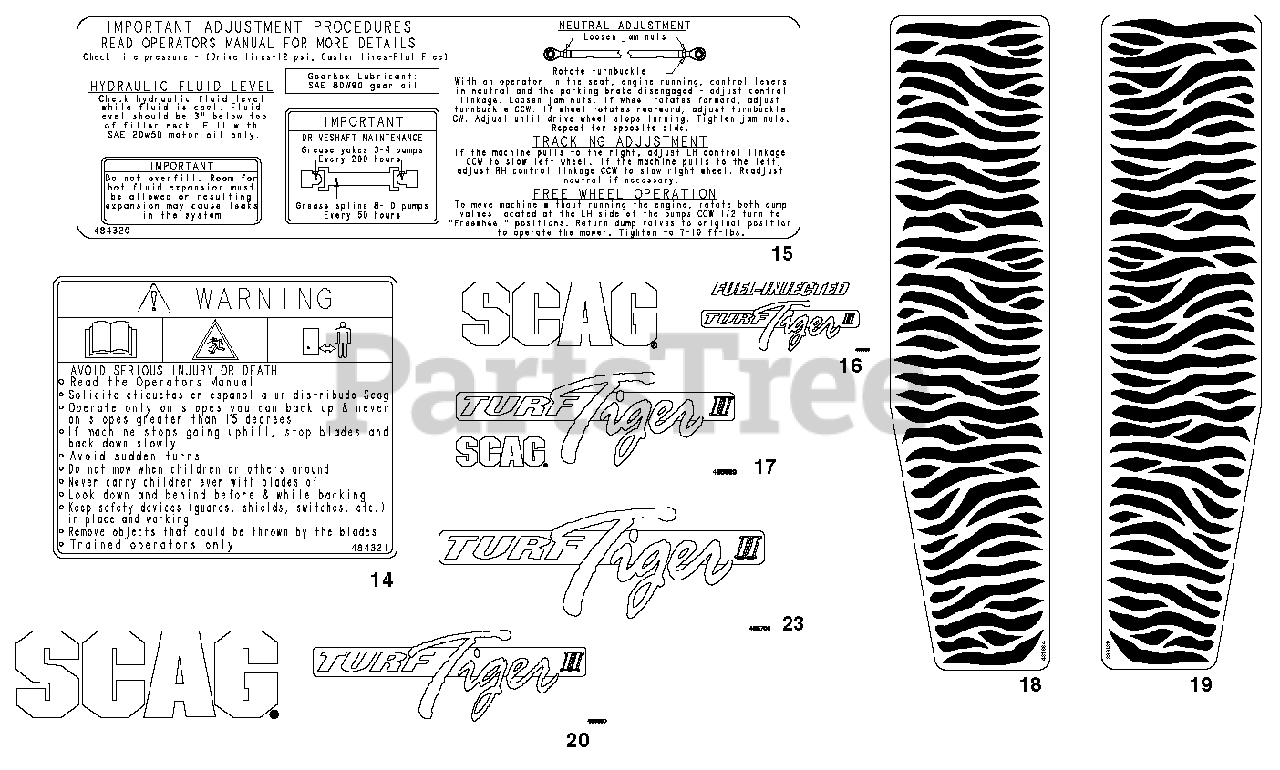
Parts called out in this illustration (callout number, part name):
14	Decal, Fuel Tank Warning
15	Decal, STT Adjustments
16	Decal, Hood - STTII Fuel Injected
17	Decal, Turf Tiger II
18	Decal, Stripes-RH
19	Decal, Stripes-LH
20	Decal, Hood - STTII
23	Decal, Turf Tiger II
